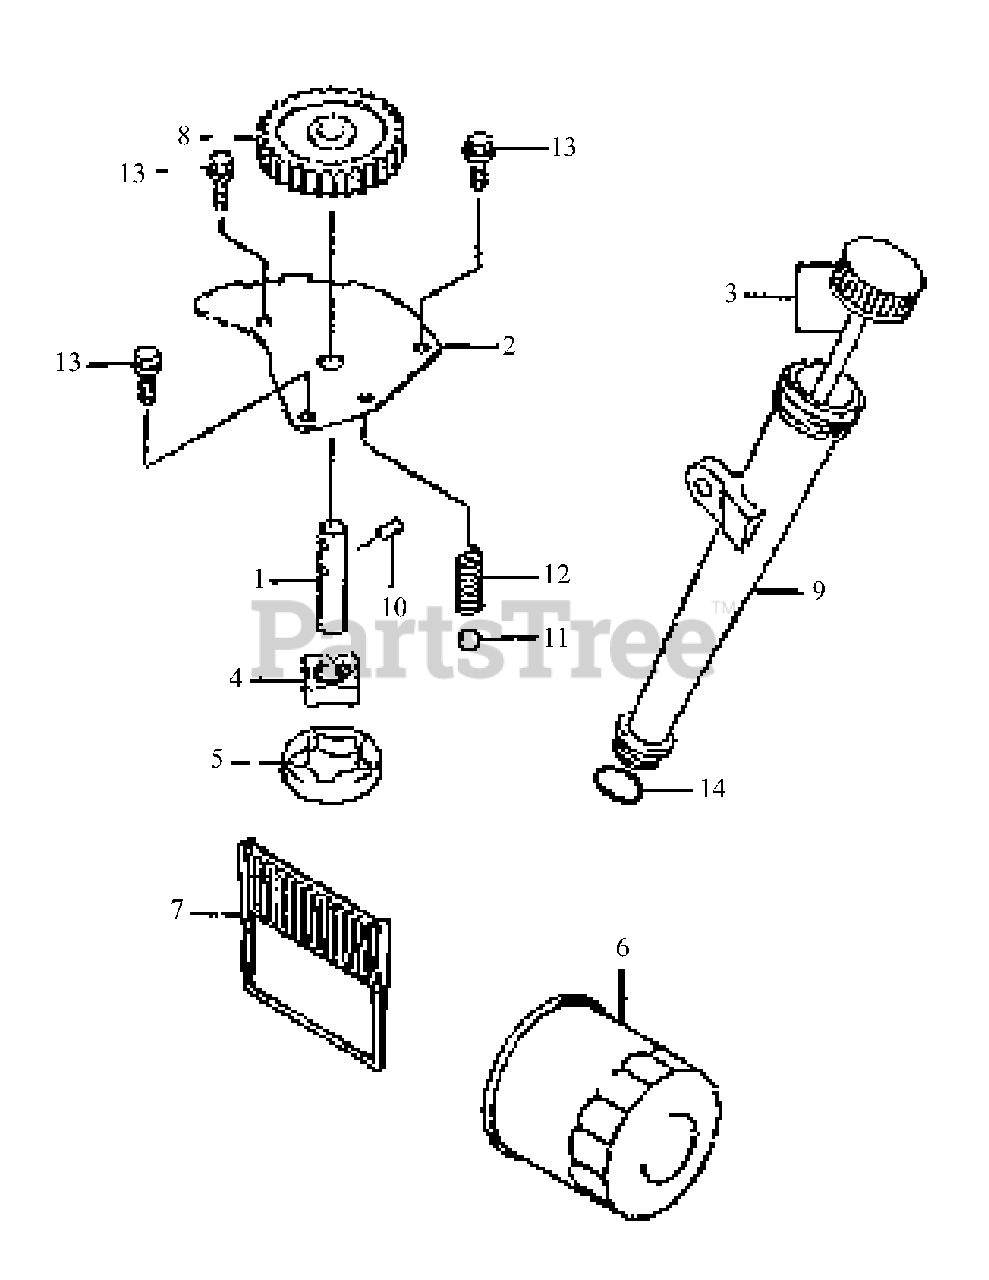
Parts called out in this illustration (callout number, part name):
1	Shaft, Oil Pump
3	Cap Assembly
4	Rotor, Pump In
5	Rotor, Pump Out
6	Filter, Oil
7	Filter, Oil Screen
8	Gear, Spur
10	Pin
13	Bolt, Flange
